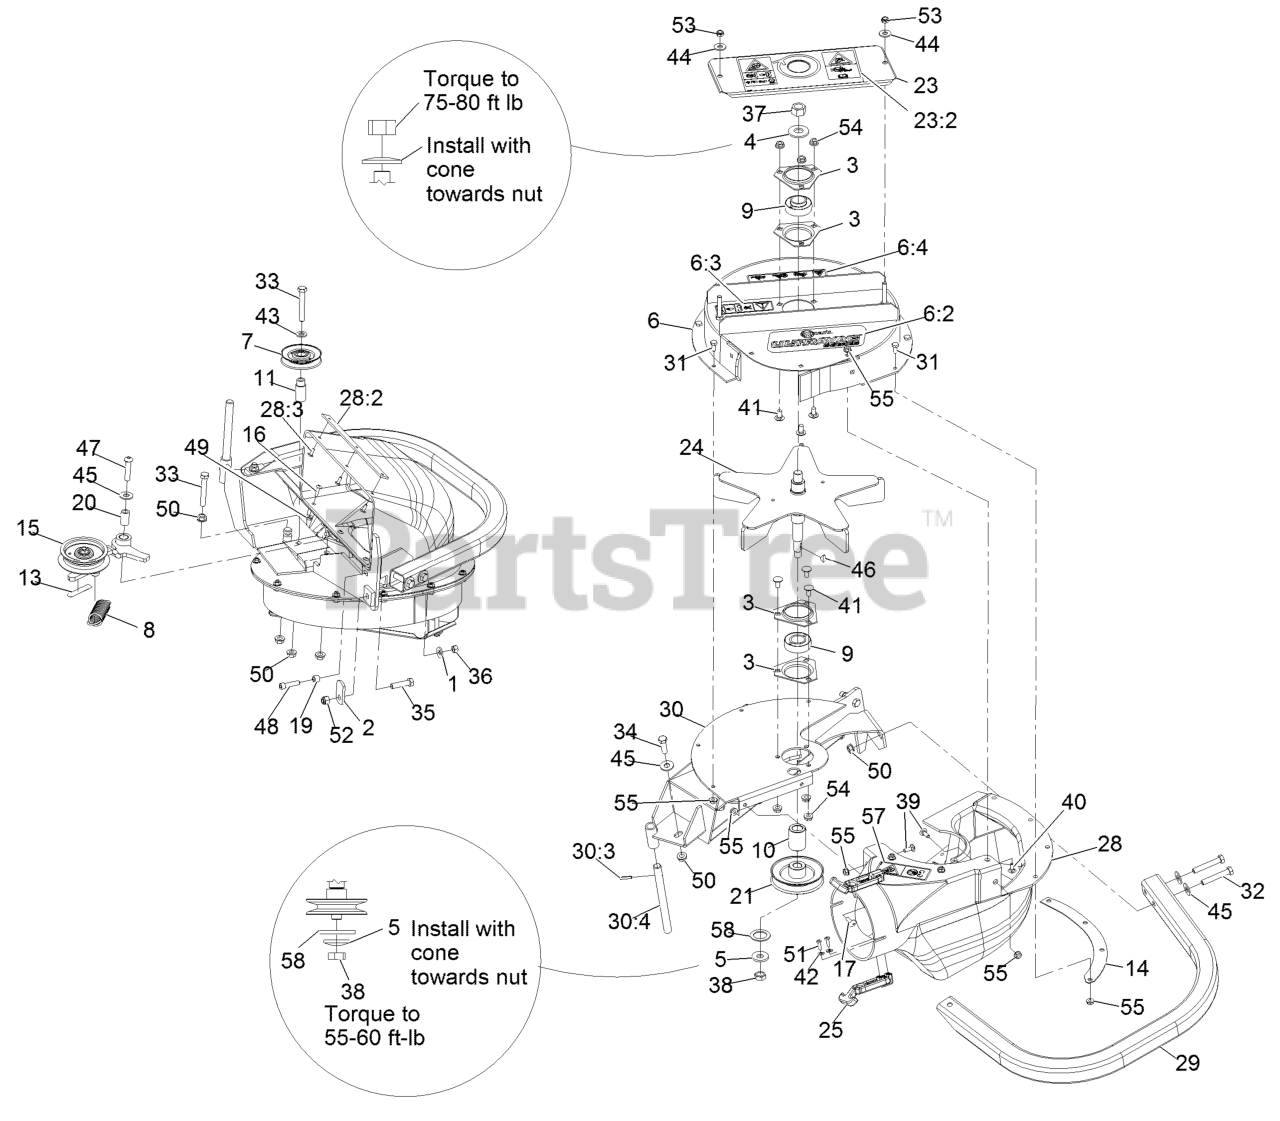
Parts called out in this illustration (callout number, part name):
1	Washer-Spring Disc 5/16
2	Latch-Catcher, Grass
3	Housing-Flange
4	Washer-Spring Disc 5/8
5	Washer-Spring Disc 1/2
6	ASM-Upper Housing Small
6:2	Decal-Ultravac S-Series
6:3	Decal-Missing, Cover
6:4	Decal-Warning Weight
7	Idler-Inside
9	Bearing
13	Decal-Warning
14	Plate-Backing, Blower
16	Screw-Truss Head #10-24 X 3/4
17	Screw-PPH 1/4-20 X 3/4
19	Bushing
20	Bushing-Pivot, Idler
21	Sheave-Blower
23	Cover, Bearing
23:2	Decal-Warning
24	Impeller
25	Latch-Rubber
28	Chute, Blower (46, 50 And 56)
28:2	Plate-Reinforcing
30	Weld, Frame Sm Blower
30:3	Rollpin 3/16 X 7/8
30:4	Shaft-Catcher, Grass
31	Screw-HH 1/4-20 X 5/8
32	Screw-HH 3/8-16 X 2 1/4
33	Screw-HH 3/8-16 X 2 1/2
34	Screw-HH 3/8-16 X 1 1/4
35	Screw-HH 3/8-16 X 1 1/2
36	Nut-Hex 5/16-18
37	Nut-Hex 5/8-18
38	Nut-Jam 1/2-20
39	Bolt-Carriage 1/4-20 X 3/4
40	Bolt-Carriage 1/4-20 X 5/8
41	Bolt-Carriage 5/16-18 X 5/8
42	Washer-#10 Std
43	Washer-3/8 SAE
44	Washer-5/16 Std
45	Washer-3/8 Std
46	Key-Woodruff 3/16 X 5/8
47	Screw-Button Head 3/8-16
48	Screw-Sh 5/16-18 X 1 1/4
49	Nut-Whizlock #10-24
50	Nut-Whizlock 3/8-16
51	Screw-PPH #10-24 X 5/8
52	Nut-Nyloc 3/8-16
53	Nut-Nyloc 5/16-18 Thin
54	Nut-Whizlock 5/16-18
55	Nut-Whizlock 1/4-20
57	Decal-Warning
